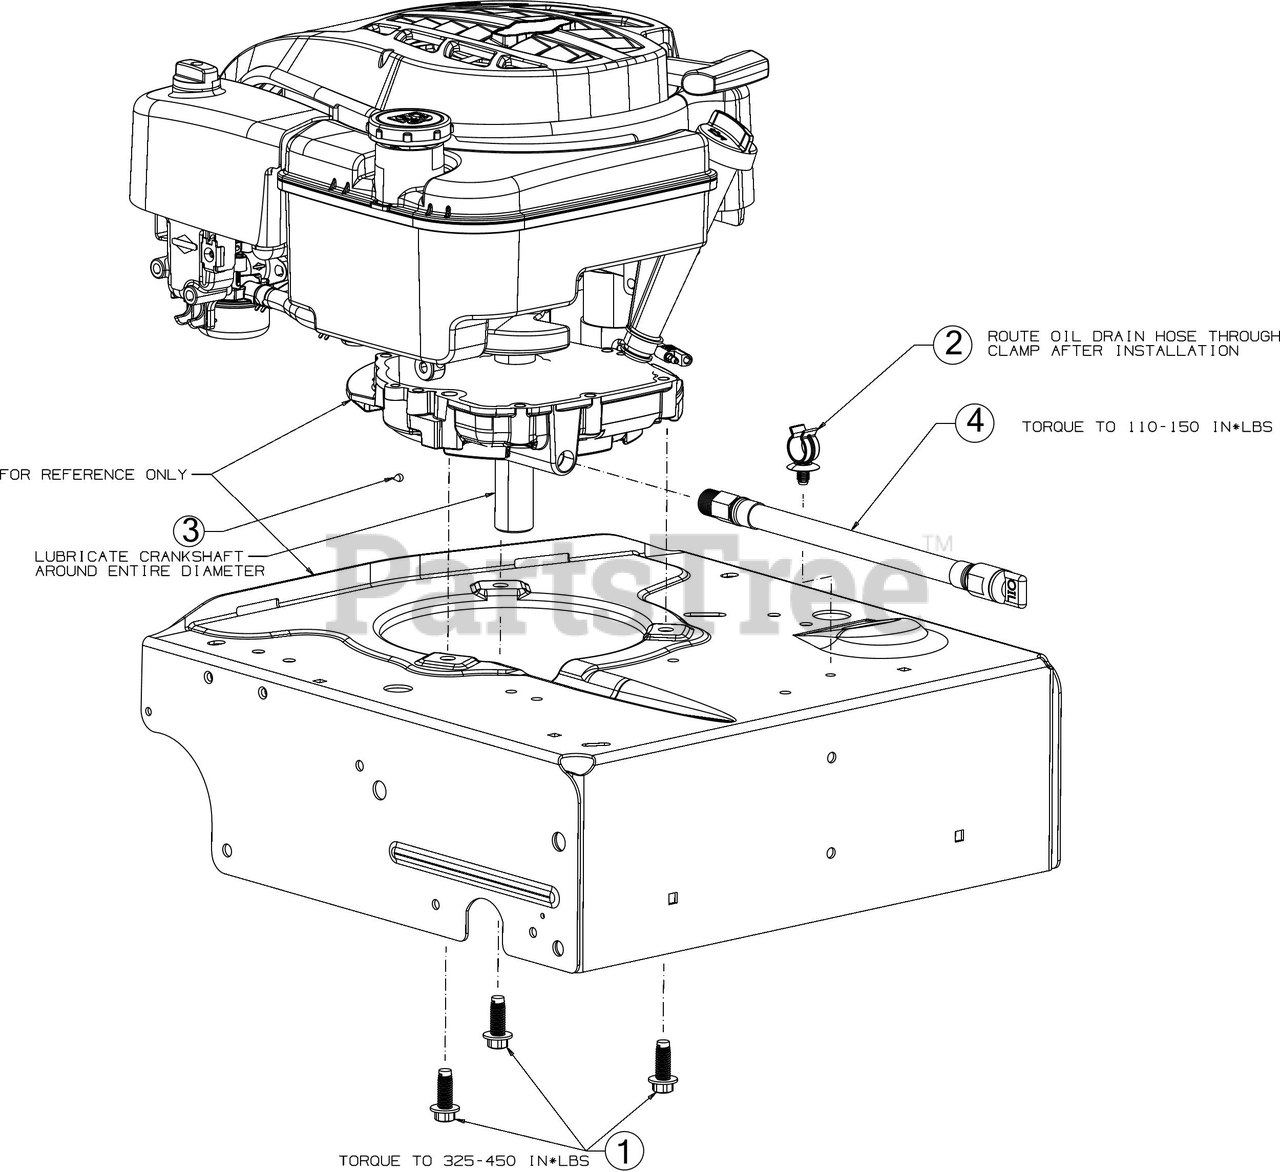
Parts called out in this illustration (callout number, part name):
1	SCREW 3/8-16 x 1
2	DRAIN HOSE CLIP
3	GREASE
4	OIL DRAIN HOSE
